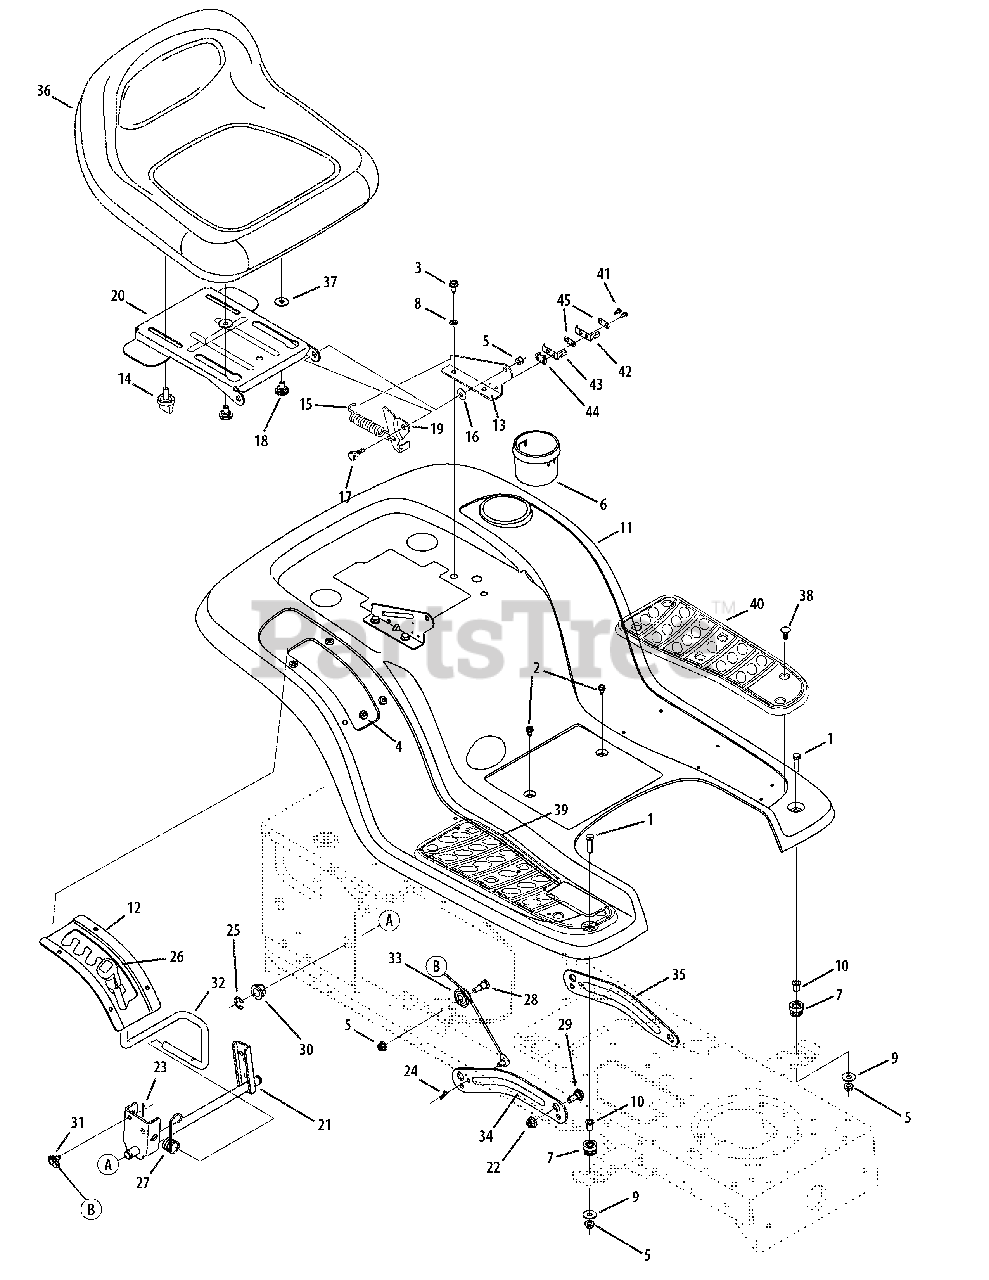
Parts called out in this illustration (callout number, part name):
1	Hex Screw, 5/16-18 x 1.25
2	Screw, 1/4-20, 0.500
3	Screw, 5/16-18, 0.750x
4	Screw, 5/16-18, 0.750
5	Nut, Flange Lock, 5/16-18, GrF
6	Cup Holder
7	Grommet, .4375 x .750
8	Lock Washer, 5/16
9	Washer, Flat,.344 x 1.0 x.063
10	Flanged Spacer
14	Knob, 3/8-16
15	Spring, Extension,.84 Dia. x 4.6
16	Wash, Flat, .340 x .688 x .065
17	Screw, Shoulder,.437 x.268
18	Shoulder Screw
19	Seat Bracket, Lift
23	Pin, Cotter,.072 Dia. x 1.13
24	Pin, Cotter, 3/32, 1.0
25	Ring, E Type,.625 Dia.
26	Grip, Handle, 1/2
27	Spring, Torsion
28	Screw, 5/16-18 x.620 Gr2
29	Scr.,Shldr, .625 x.165,
30	Bearing, Hex Flange
31	Cable, Lift, 16.16
32	Handle, Lift
33	Pulley, Roller
36	Low Back Seat
37	Flat Washer, .406 x .875 x .059
38	Ratchet Clip
39	RH Foot Pad,Rubber
40	LH Foot Pad, Rubber
41	Screw, #8-18 x.50
42	Spring Switch, Outer
43	Spring Switch, Inner
44	Plate, Insulator Boss
45	Plate, Insulator
